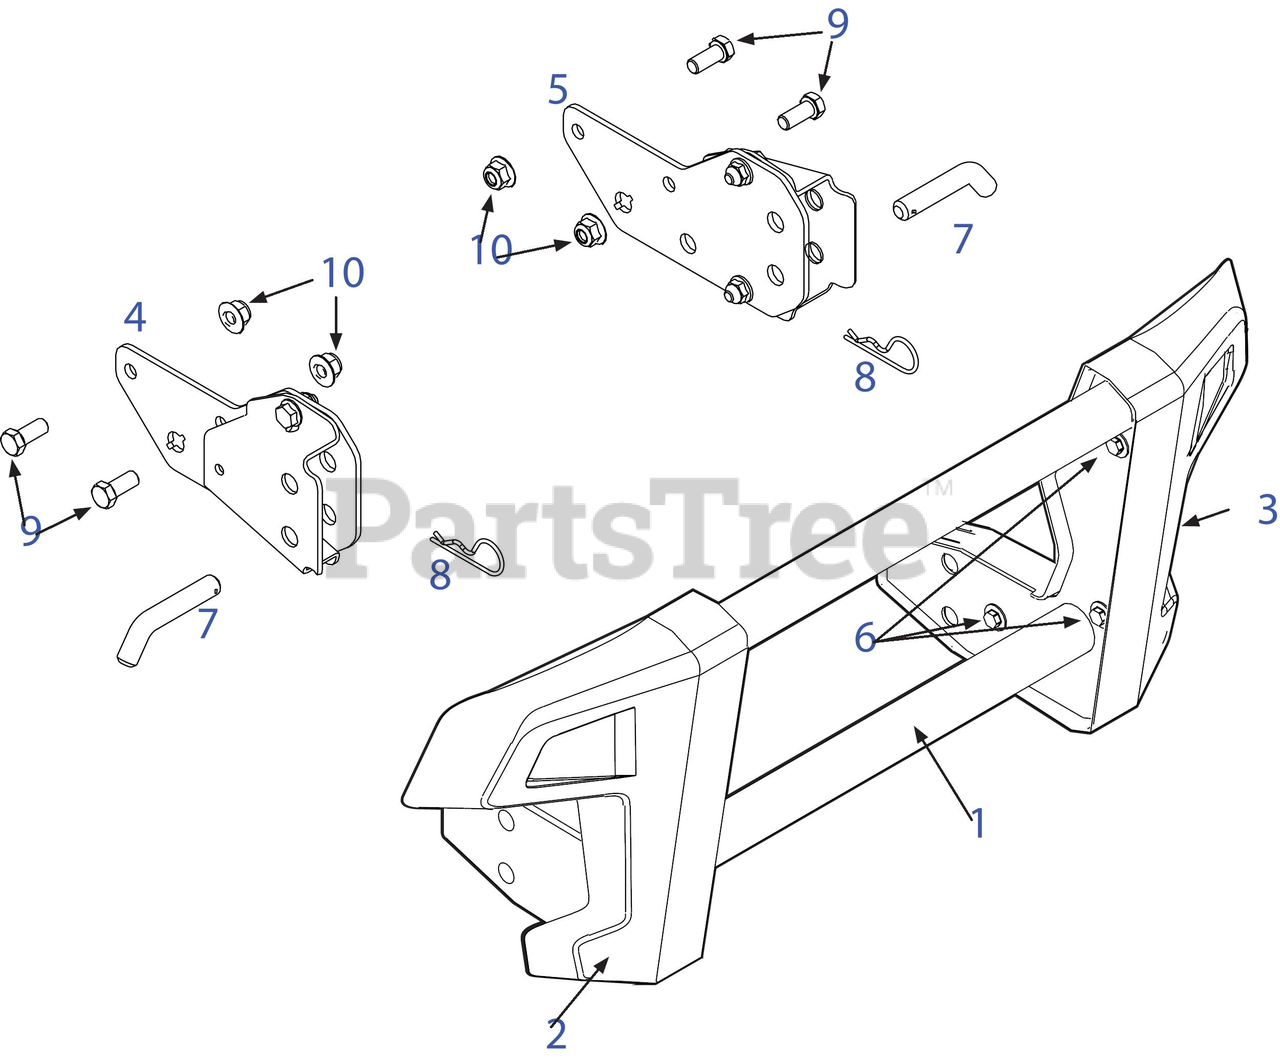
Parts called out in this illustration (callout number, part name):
2	Guard, Fascia RH
3	Guard, Fascia LH
4	Bracket Assembly, Front RH
5	Bracket Assembly, Front LH
6	Screw, 5/16-14 X .750
7	Pin, 0.500 X 1.70
8	Internal Cotter Pin
9	Screw 3/8-16 X .880 GR5
